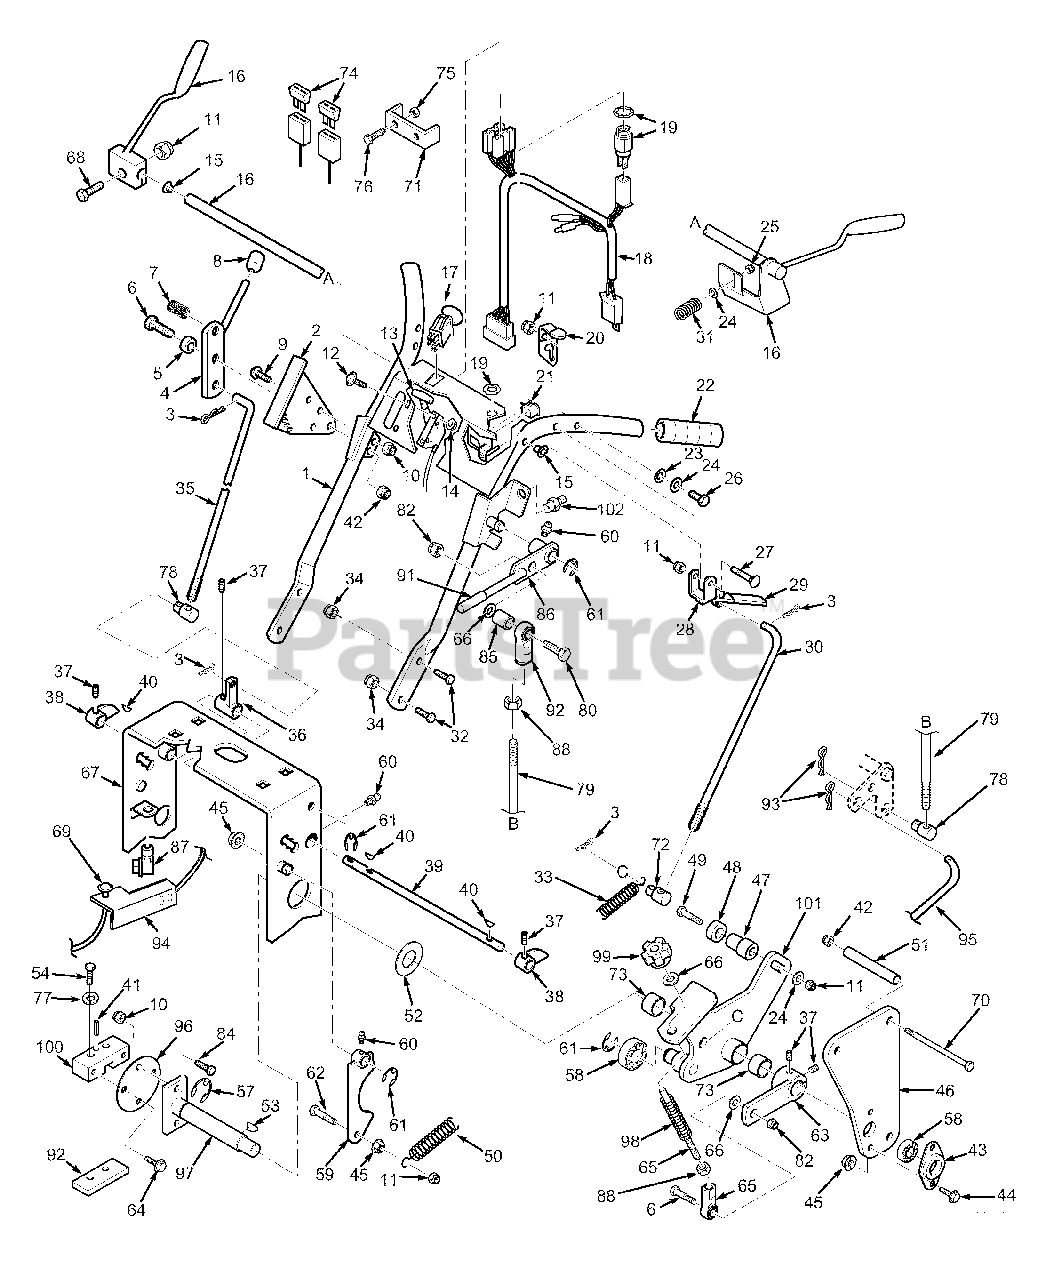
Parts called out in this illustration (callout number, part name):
1	Upper Handle Wlmt. W/Decals
2	Quadrant, Speed Control
3	Hairpin, .094 x 1.19
4	Lever, Speed Adjustment
5	Bushing, Speed Adjustment Lever
6	Hex Head Bolt, 3/8-16 x 1.5"
7	Ball Plunger
8	Knob, Speed Adjustment
9	Capscrew, 1/4-20 x 3/4" FHHS
10	Nut, 1/4-20 Elastic Stop
11	Nut, 5/16-18 Elastic Stop
12	Screw, #10-32 x 1/2" PW HD
13	Throttle Control
14	Nut, #10-32 Serr. Flange
15	Bushing
16	Handle, Oper. Presence-RH
17	Switch,Elec.Clutch Eng.
18	Wire Harness, Electric Start
19	Key Switch, Electric Srt.
20	Neutral Latch-RH
21	Switch, Neutral Interlock
22	Grip
23	Washer, Curved Spring
24	Flat Washer
25	Nut, 5/16-18 Elastic Stop
26	Hex Head Bolt, 5/16-18 x 2"
27	Hex Hd. Bolt, 5/16-18 x 2.5"
28	Lever, Steering Control
29	Grip, Steering Control
30	Rod, Steering Control
31	Spring, Handle Return
32	Capscr., 3/8-16 x 1" Ser. Flange
33	Spring
34	Nut, 3/8-16 Serr. Flange
35	Rod Speed Control
36	Bellcrank, Speed Control
37	Setscrew, 1/4-28 x .25"
38	Cam, Speed Control
39	Jackshaft, Speed Control
40	Key, 1/8 x 1/2" Woodruff
41	Roll Pin, 3/16-.75
42	Nut, Elastic Stop 3/8-16
43	Flange, Bearing
44	Capscrew, 5/16-18 x 1" Serr. Flg.
45	Nut, 5/16-18 Serrated Flange
46	Plate, Side
47	Support, Neutral Support
48	Bearing, Speed Ctrl. Bellcrank
49	Hex Head Bolt, 5/16-18 x 1-3/4"
50	Spring, Return
51	Spacer, Side Plate
52	Flat Wshr., 3/4-.766 x 1.25 x .035
53	Key, Woodruff, 3/16 x .75"
54	Bolt, Hex Head, 1/4-20 x 1.25
57	Clip, Retaining .750 diameter
58	Bearing, Ball Neutral Return
59	Cam, Neutral
60	Grease Fitting, 1/4-28 UNF
61	Retaining Ring, 5/8 Ext. "E"
62	Hex Head Bolt, 5/16-18 x 1"
63	Lever, Speed Control
64	Bolt, Serr. Flange 1/4-20 x.75"
65	Linkage Assembly
66	Flat Wshr., 15/16 x .3906 x 12 ga
67	Deck, Engine 20" Wide
68	Hex Head Bolt, 5/16-18 x 1.25"
69	Choke Control
70	Bolt, Hex Head 3/8-16 x 4.25"
71	Fuse Holder
72	Swivel Joint, Steering Rod
73	Bushing
74	Blade Fuse, 20A
75	Nut, #10-32 Elastic Stop
76	Screw, #10-32 x 1.5" Phillips
77	Lockwasher, 1/4"
78	Swivel Joint
79	Rod, Brake Lever
80	Hex Hd. Bolt, 3/8-16 x 1.75"
82	Nut, 3/8-16 Elastic Stop
84	Bolt, 1/4-20 x .75"
85	Spacer
86	Parking Brake Lever with Grip
87	Switch, Safety
88	Nut, 3/8-24
91	Grip, Parking Brake
92	Plate, Threaded
93	Hairpin, .094 x 1.62"
94	Bracket, Choke Mtg.
95	Rod, Lower Brake
96	Plate, Coupler
97	Shaft, Pump Control
98	Spring
99	Knob, Tracking Adjustment
100	Block, Pump Control
101	Control, LH
102	Switch, Parking Brake
